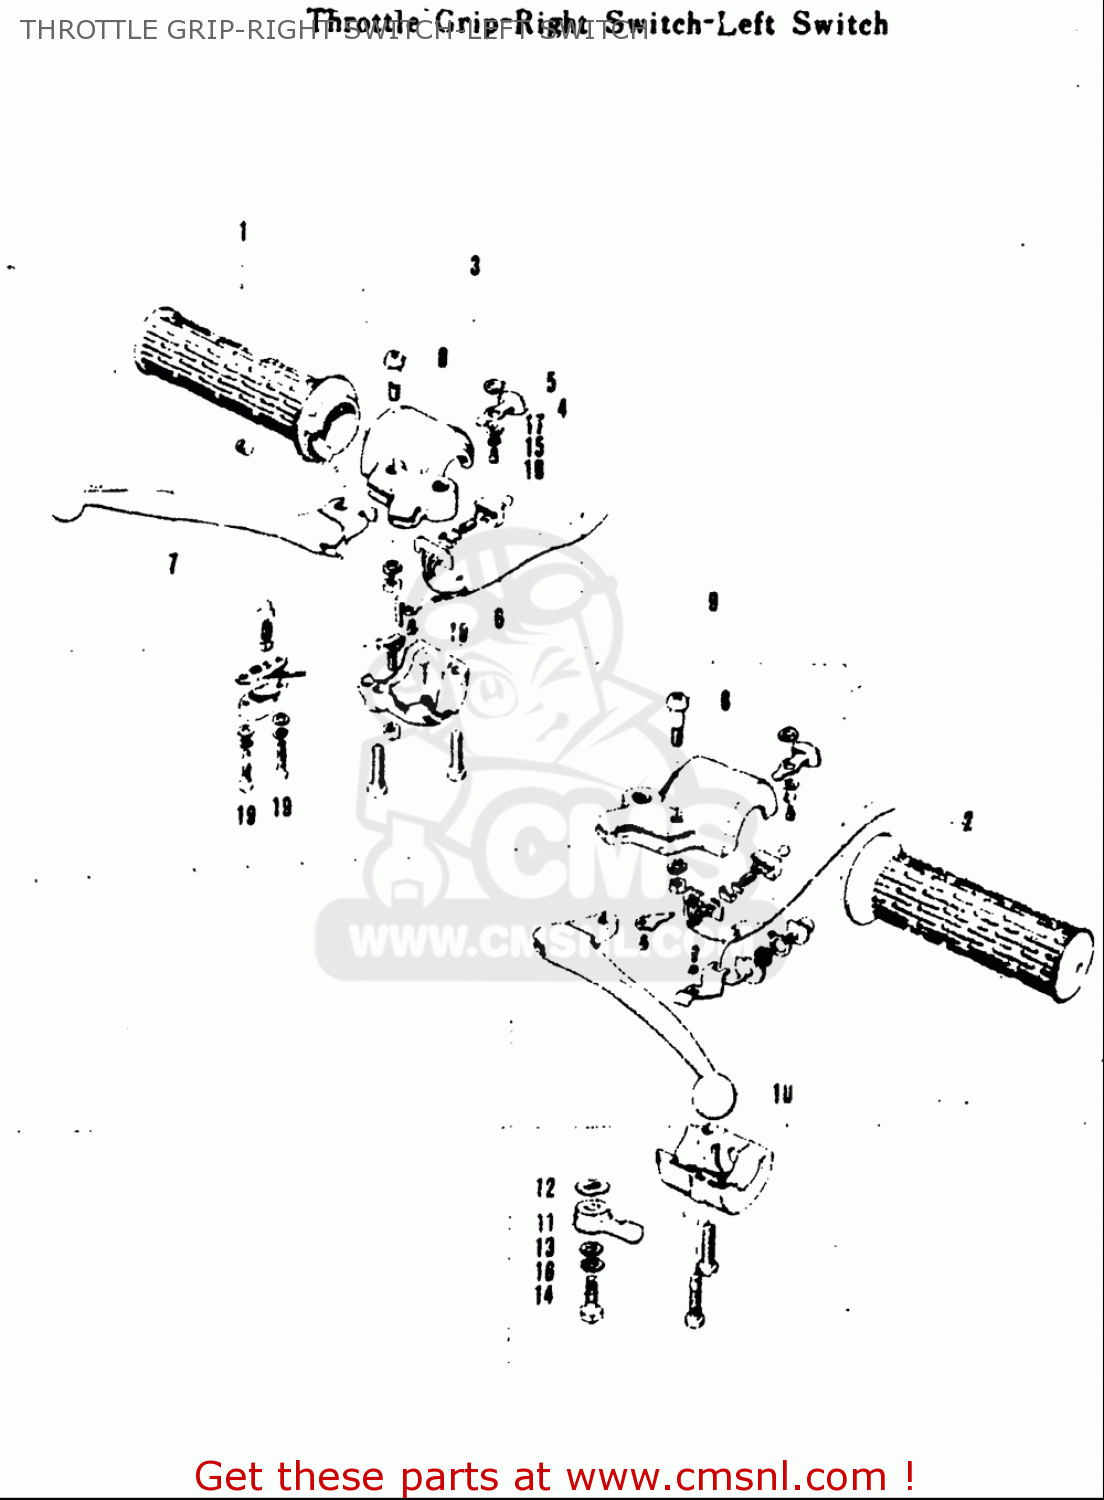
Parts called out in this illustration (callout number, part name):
1	GRIP,THROTTLE
7	LEVER,BRAKE
8	BOLT,LEVER PIVOT
10	LEVER,CLUTCH
11	LEVER,STARTER
12	WASHER,ADJUSTER
13	WASHER(6.5X16X1)
15	WASHER,LOCK
16	WASHER,LOCK
17	WASHER
